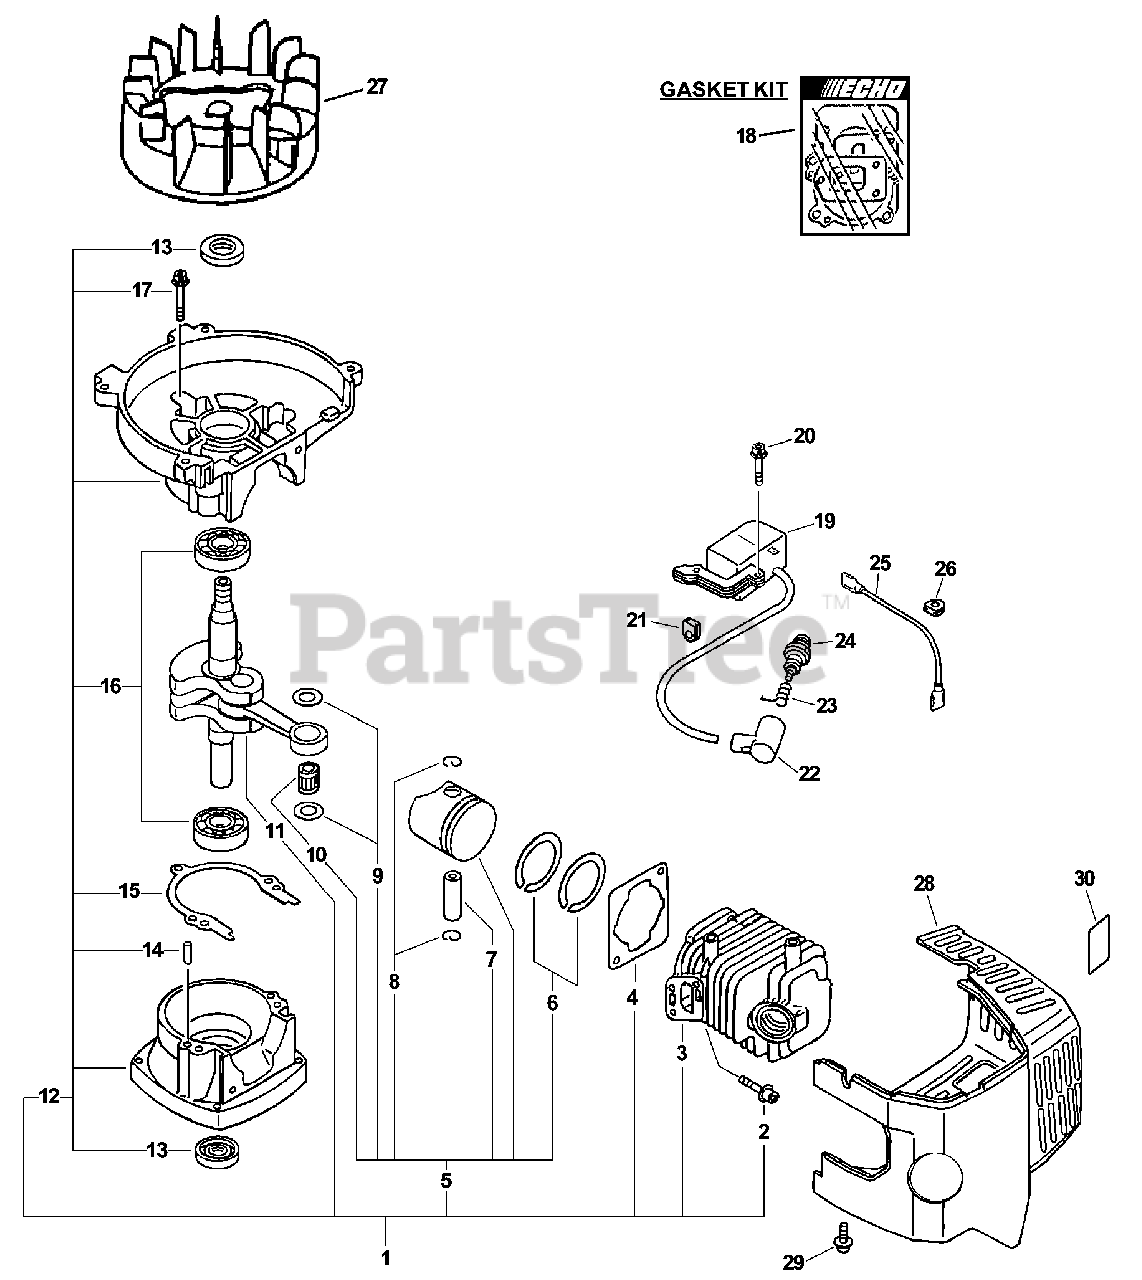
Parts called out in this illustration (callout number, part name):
1	SHORT BLOCK
2	BOLT 5×22
3	CYLINDER
4	GASKET, CYLINDER
5	PISTON KIT
6	RING, PISTON
7	PIN, PISTON 8
8	RING, SNAP
9	WASHER, THRUST
10	BEARING, NEEDLE
11	CRANKSHAFT ASSY
12	CRANKCASE KIT
13	SEAL, OIL 12
14	PIN, LOCATING 4
15	GASKET, CRANKCASE
16	BEARING, BALL - 6201 C3
17	BOLT 5×28
18	GASKET KIT
19	COIL, IGNITION
20	SCREW 4×22
22	CAP, SPARK PLUG
23	TERMINAL, SPARK PLUG
24	SPARK PLUG - BPM-7Y
25	LEAD
27	FLYWHEEL
28	COVER, ENGINE
29	BOLT 4×20
30	LABEL, CAUTION - HOT
